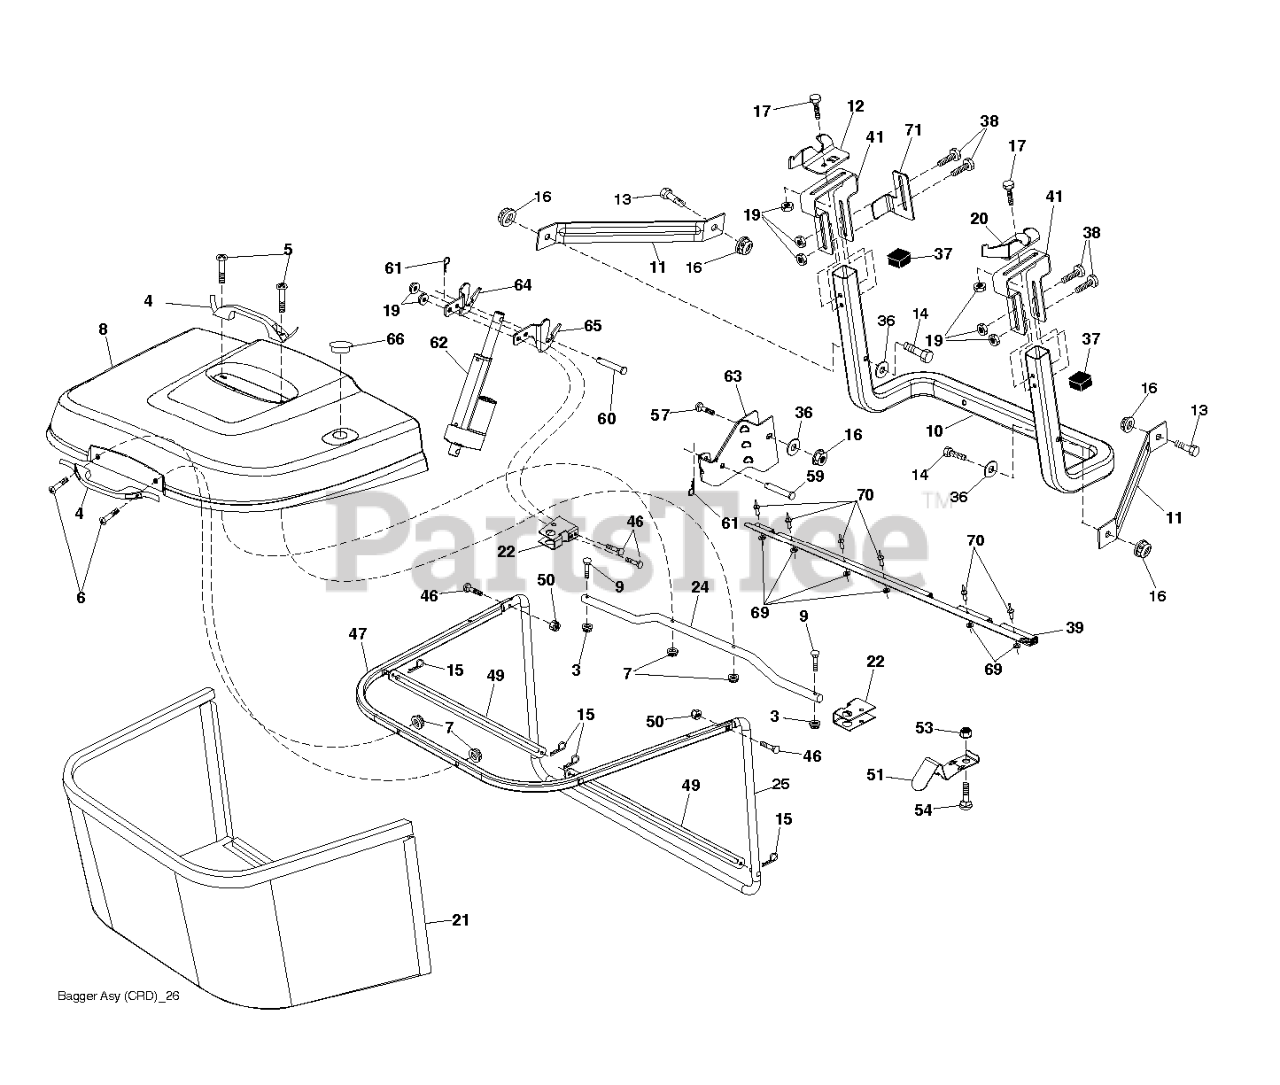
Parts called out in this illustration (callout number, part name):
3	NUT T
4	HANDLE.BAGGER.W/LVRS.BLK.CRD
5	SCREW.PAN.HEAD
6	REPL BY 532 75 00-29
8	BAGGER.COVER.SEAL.ASM.
9	Bolt Carriage 1/4-20 x 2.25d x Gr.5
10	TUBE
11	BRACKET.SUPPORT.UPPER.BAG.CRD
12	BRKT PIVOT
14	BOLT-HEX EAK
15	RETAINER-SPRNG RB
16	NUT LOCK FLG 3/8-16 UNC
17	RP BOLT 5/16-18 X3/4 ZN/YEL GR
19	NUT LOCK HEX FLANGE 5/16-18
20	BRKT.PIVOT.RH.CRD
21	BAGGER.ASM.CRD.2007
22	BRACKET.BAGGER.SD.ELECTRIC.CRD
24	TUBE.PIVOT.BAG.CRD.BLACK
25	PIPE
36	WASHER
37	Plug Support Bagger CRD
38	BOLT.5/16-18X2.5
39	SEAL.BAGGER.CRD
41	BRACKET.BAGGER.SD.ELECTRIC.CRD
46	BOLT.CARRIAGE.5/16-18
47	PIPE
49	ROD
50	NUT.71038.31-18.HEX.NYLOCK
51	LATCH
53	NUT
54	BOLT
57	BOLT
61	RETAINER M
69	WASHER
70	RIVET RIVET POP
